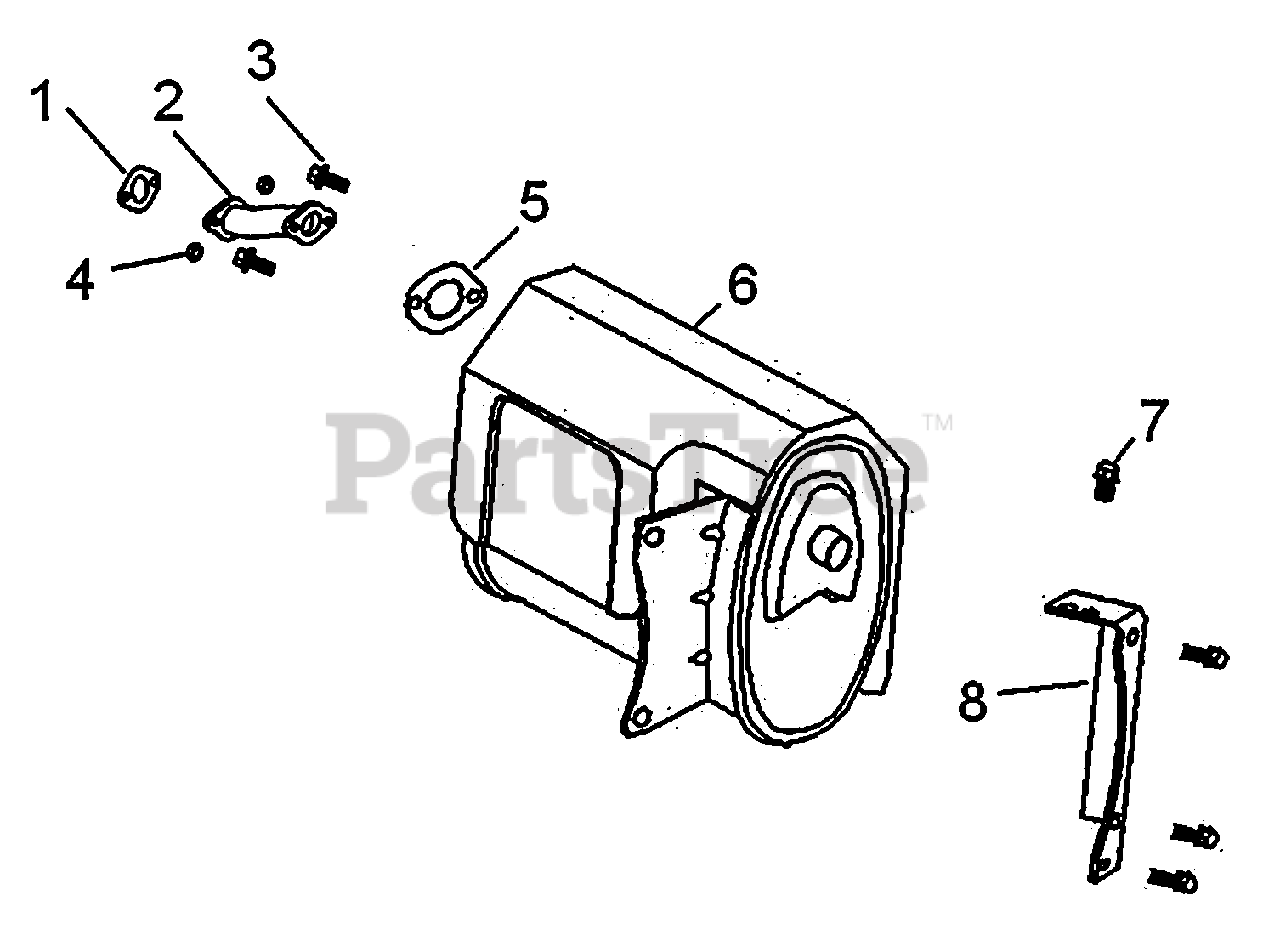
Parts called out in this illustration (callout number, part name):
1	GASKET, EXAUST, CYLINDER
2	MANIFOLD, EXHAUST
3	BOLT, FLANGE, 8X25
5	GASKET, EX., PIPE
7	BOLT, FLANGE, 8X16
8	STAY COMP., MUFFLER
